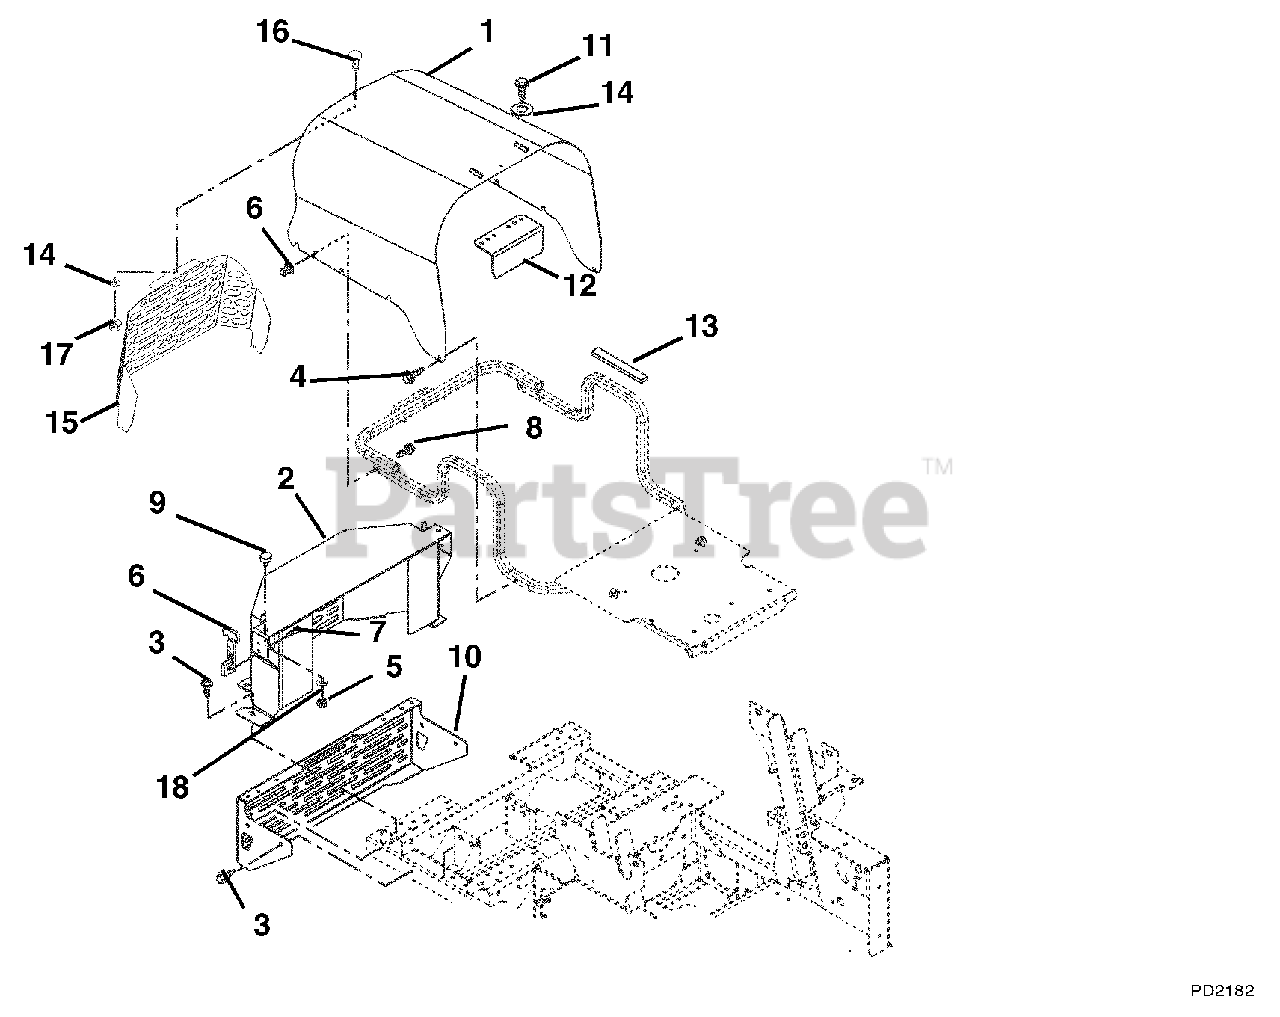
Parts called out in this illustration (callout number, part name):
1	Hood (038, 039)
1	Hood (036, 037, 309)
2	Weldment, Belt Guard (036, 037)
2	Weldment, Belt Guard (038, 039, 309)
3	Screw-Tapping .38-16 x .75 Hex Washer Head
4	Screw-Tapping .38-16 x .50 Hex Washer Head
5	Nut-Hex .31-18
6	Latch-Rubber
7	Screw-Machine 10-24 x .50 Hex Washer Head
8	Screw-Machine 10-24 x 1.50 Hex Washer Head
9	Button, Bumper
10	Bumper-Rear
11	Screw-Tapping .25-20 x .50 Hex Washer Head
12	Cover, Rad
13	VHB Tape
14	Washer-Flat-Steel .281 x .62 x .065
15	Guard, CE Diesel (038, 039, 309)
16	Bolt-Round Head Square Neck .25-20 x .50 Grade 5 (038, 039, 309)
17	Nut-Locking-Top-Flange .25-20 (038, 039, 309)
18	Washer-Locking .31 x .078 Regular
